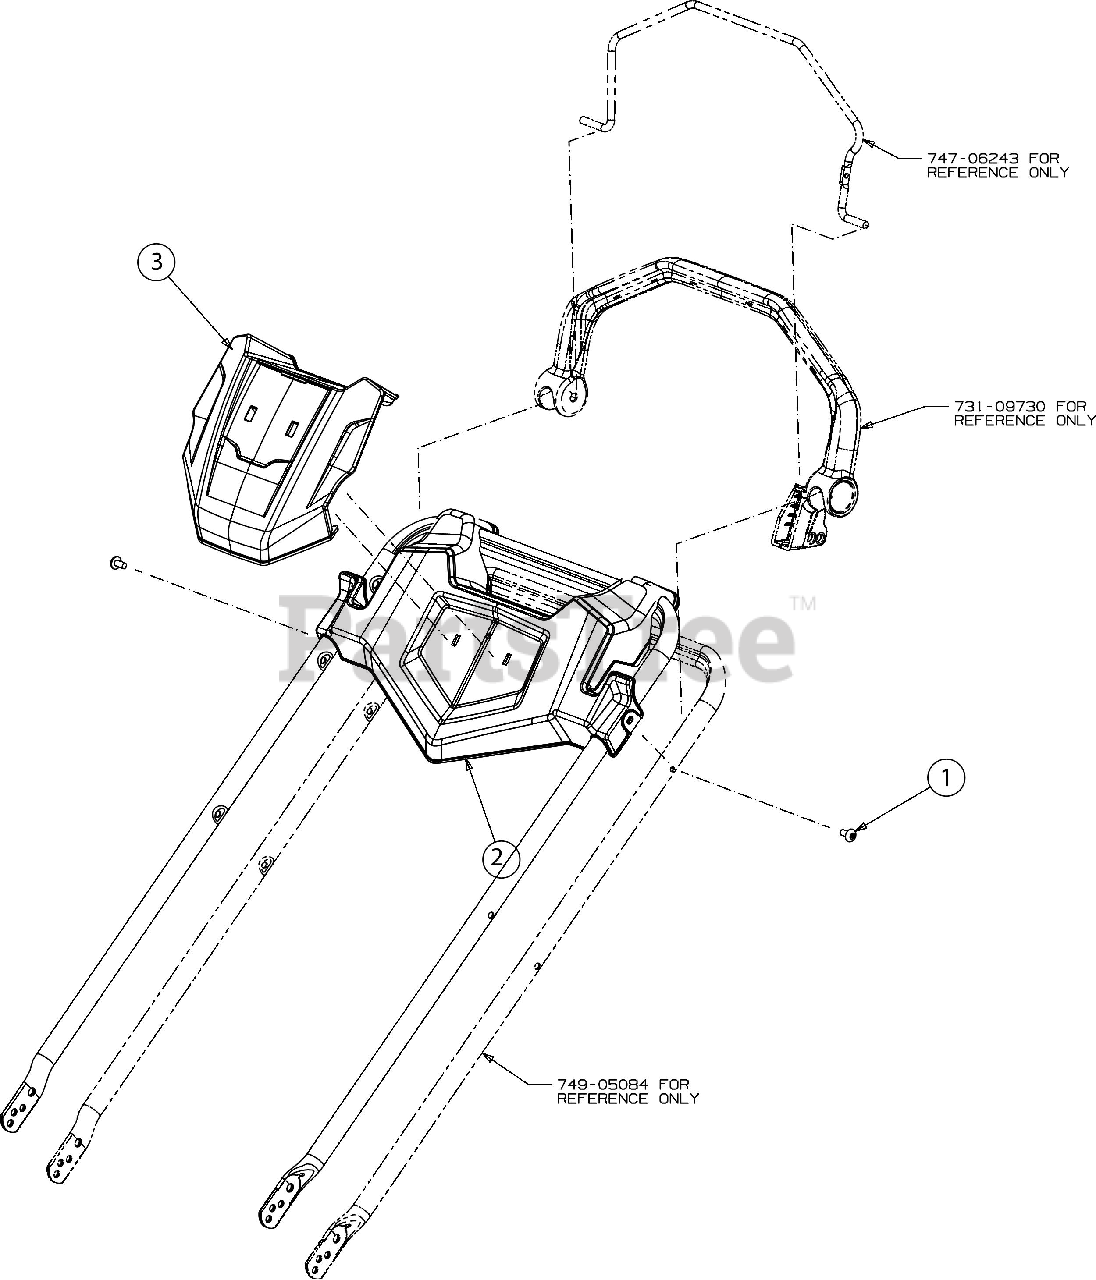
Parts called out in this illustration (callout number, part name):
1	SCREW 1/4-14 X .625
2	HANDLE CONSOLE
3	CONSOLE TRIM PIECE
